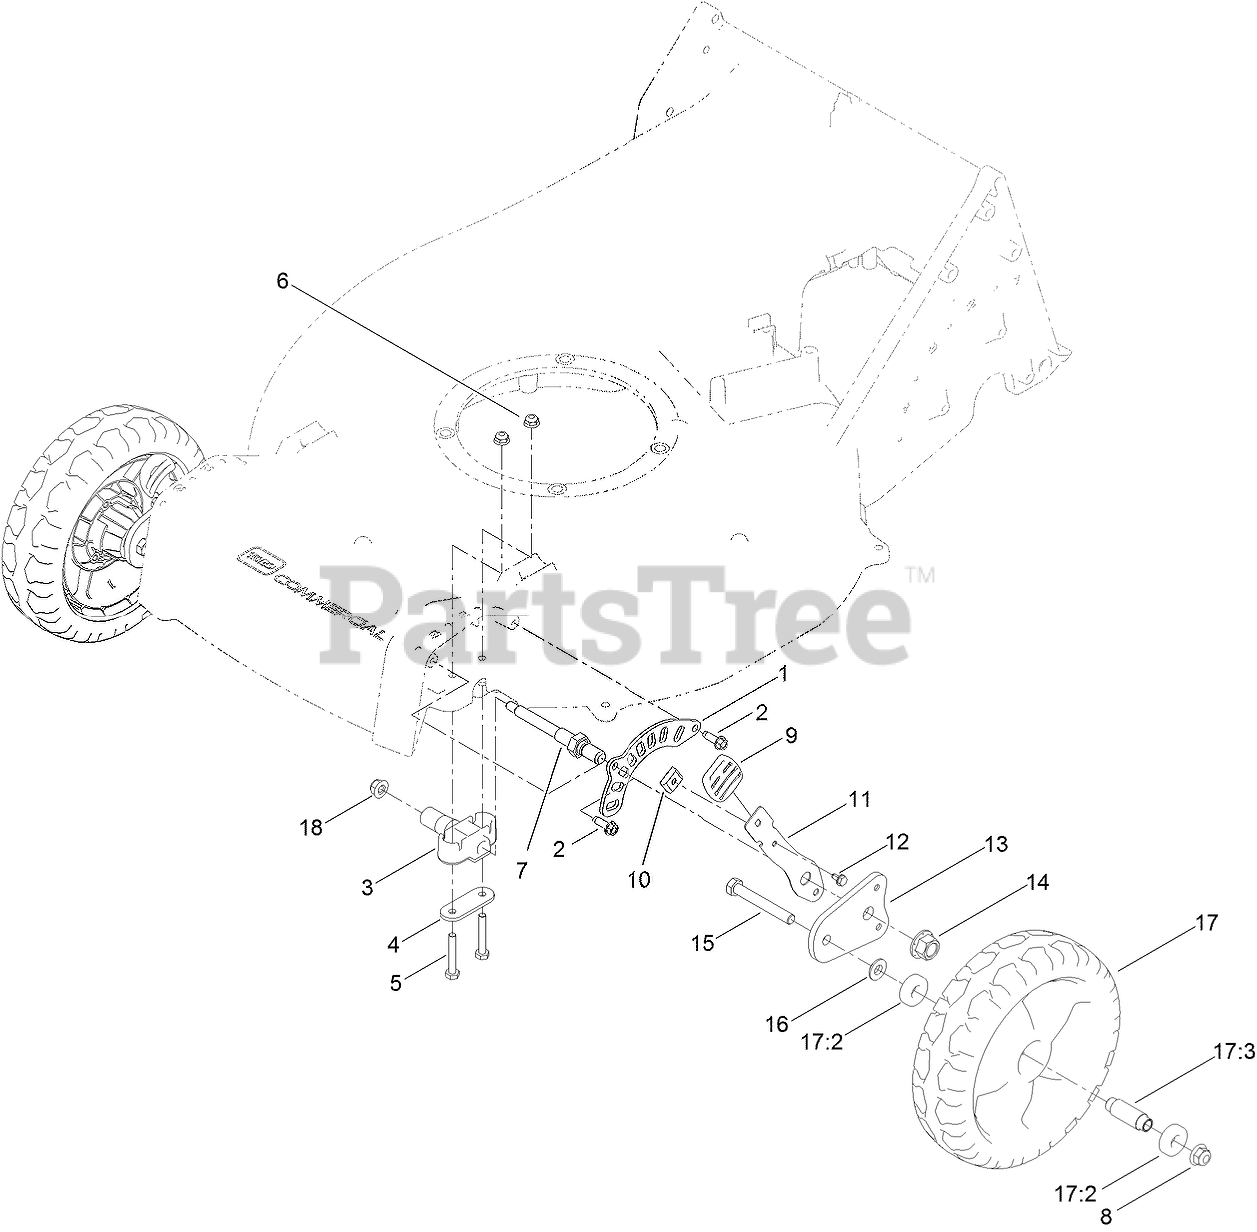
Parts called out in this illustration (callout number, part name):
1	PLATE-HOC, FRONT
2	SCREW-HWHTF
3	BUSHING-AXLE, FRONT (HOC)
4	RETAINER-BUSHING, AXLE
5	SCREW-HH
6	NUT-HF
7	AXLE-FRONT HOC
8	NUT-HF, NI
9	KNOB-LEVER, HOC
10	KEY-ARM, SPRING
11	ARM-SPRING
12	SCREW-HWH
13	ARM-PIVOT, FRONT
14	NUT-LOCK
15	SCREW-HH
16	SPACER-COVER, WHEEL
17:2	BEARING-BALL
17:3	SPACER
18	NUT-HF, NI
